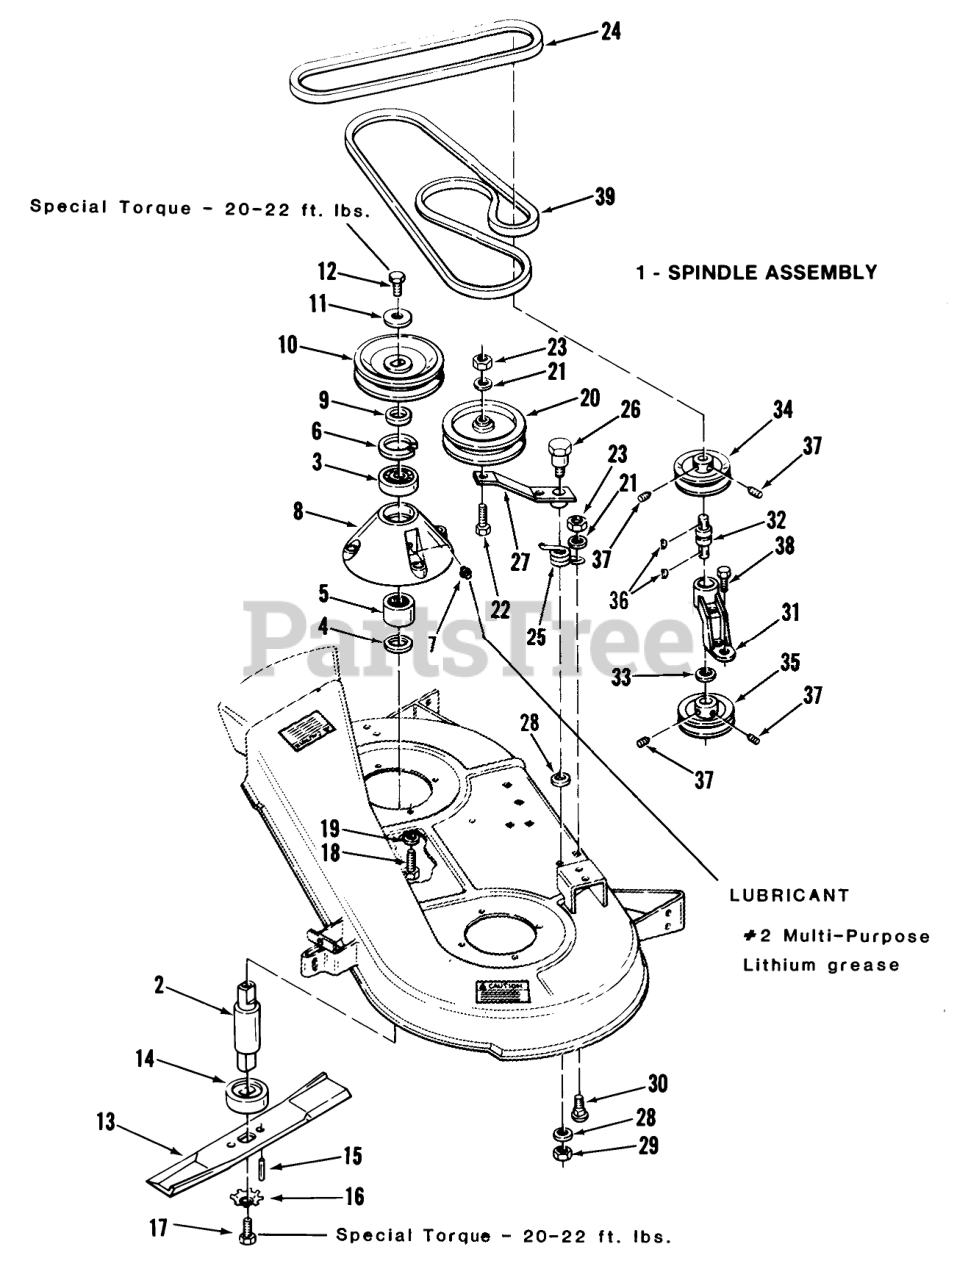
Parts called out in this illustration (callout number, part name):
1	Spindle Assembly (Includes Items 2 Thru 8)
2	SPINDLE MOWER
3	BEARING-BALL
4	OIL SEAL
5	BEARING-NEEDLE
6	INT SNAP RING
7	Fitting-Grease
8	HOUSING
9	SPACER
10	PULLEY-BLADE
11	WASHER
12	Bolt
13	S/A BLADE KIT
14	Spindle Cup
15	SPIROL ROLL PIN
16	WASHER
17	Bolt
18	Bolt
19	LOCKWASHER
20	Idler Pulley
21	Washer
22	Bolt
23	Nut
24	V-BELT
25	SPRING-TORSION
26	BOLT-SHOULDER
27	Idler Arm
28	WASHER
29	NUT-JAM(7/16-14)
30	Bolt
31	HOUSING DRIVE BRG R
32	BEARING-INT SHAFT
33	Snap Ring
34	PULLEY
35	PULLEY-SPLIT
36	KEY-WOODRUFF
37	Set Screw
38	Bolt
39	BELT-V MOWER
